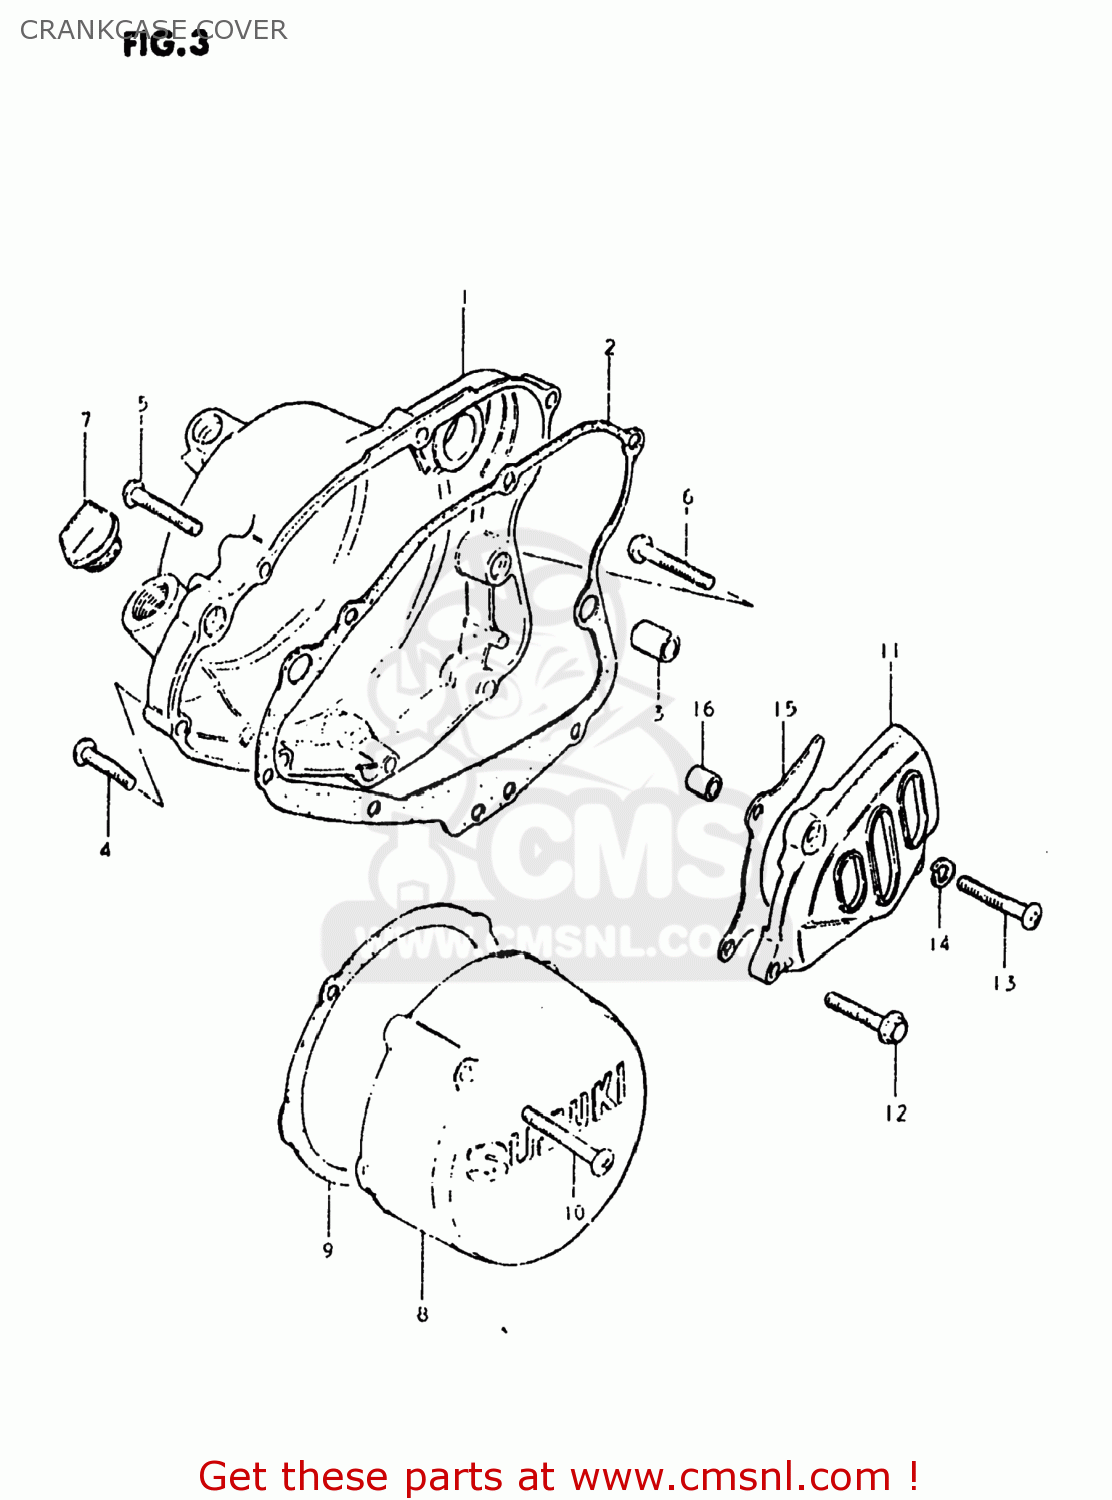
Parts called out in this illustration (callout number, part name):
1	COVER,CLUTCH
2	GASKET,CLUTCH COVER (MCA)
3	PIN
4	SCREW 6X30
5	SCREW
6	SCREW (6X45)
7	PLUG,OIL FILTER
8	COVER,MAGNETO
9	GASKET,MAGNETO COVER (NAS)
10	SCREW
11	COVER,ENGINE SPROCKET
12	BOLT 6X35
13	SCREW (6X45)
14	LOCK WASHER
15	PLATE,CHAIN FRONT GUIDE
16	SPACER(6.5X10.5X12)
